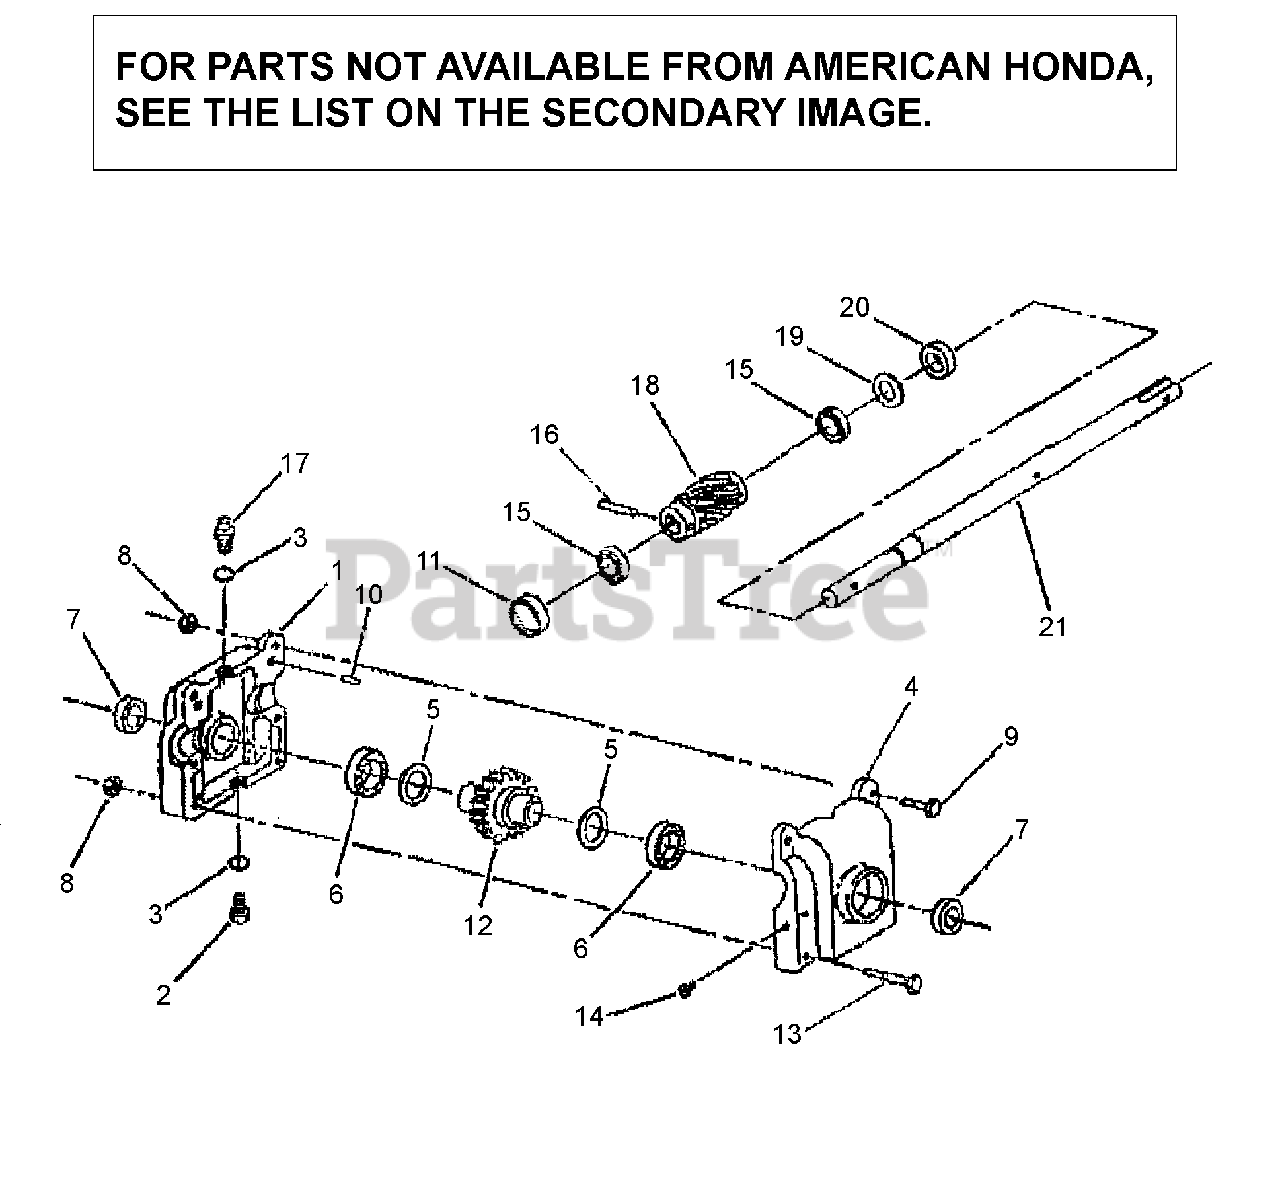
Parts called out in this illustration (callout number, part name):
1	CASING
2	PLUG
3	O-RING
4	CASING ELLO
5	SHIM
6	BEARING
7	SEAL, DOUBLE LIP
10	PIN, SPRING
11	CAP (1 9/16")
14	PLUG (1/4")
15	BEARING (NOT AVAILABLE)
16	PIN, SPRING
19	SHIM
20	OIL SEAL
